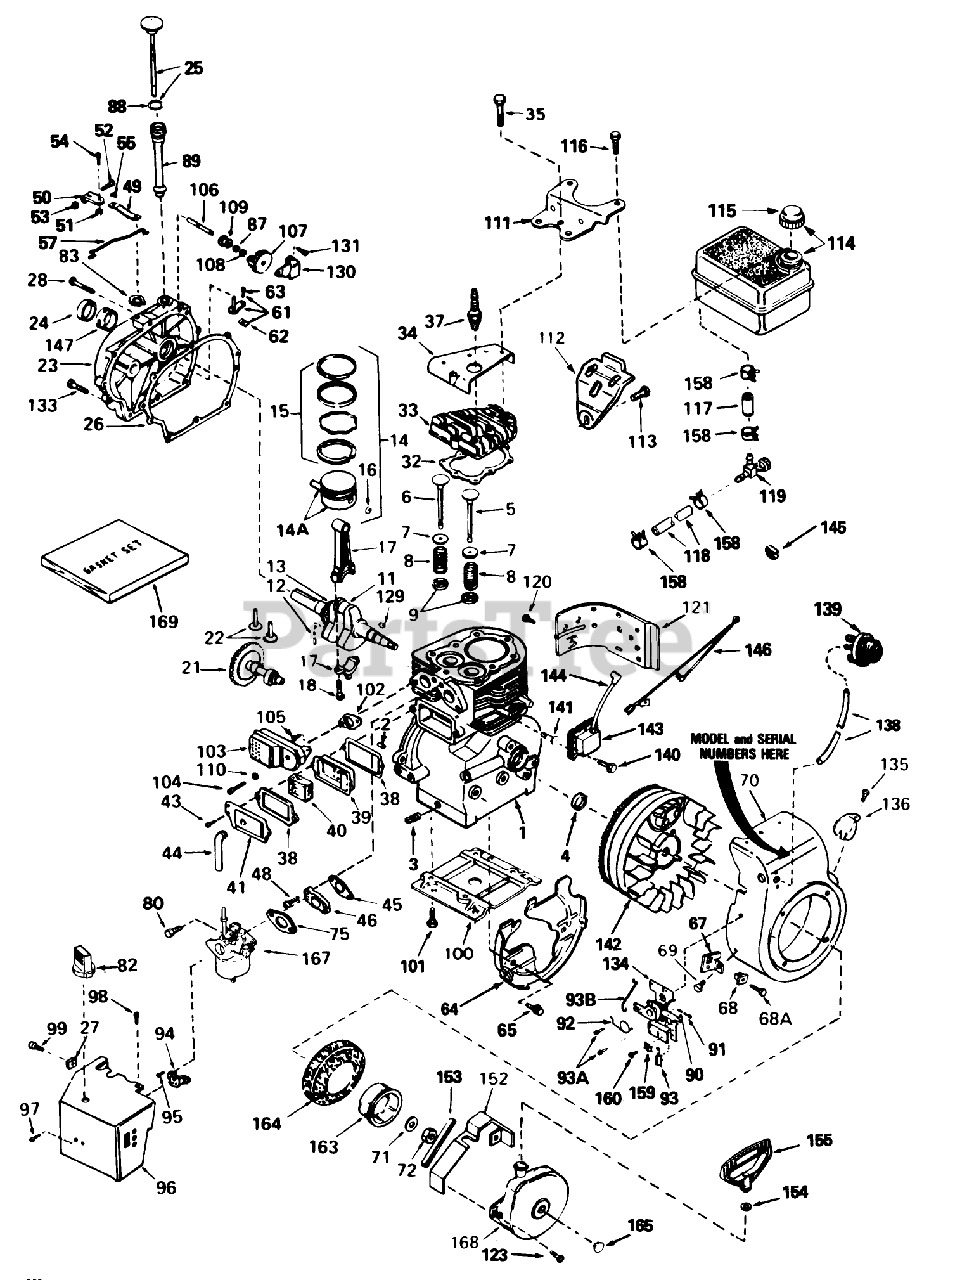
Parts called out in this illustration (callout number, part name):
1	Cylinder Assy. (Incl. Ref. #2, 3 4)
2	Pin-Dowel
3	Plug-Drain, Oil (SQH 1/4-18)
4	Oil Seal
5	Valve, Intake (Standard)(Incl. No. 9)
5	Valve, Intake (1/32" oversize)(Incl. No. 9)
6	Valve, Exhaust (Standard)(Incl. No. 9)
6	Valve, Exhaust (1/32" oversize)(Incl. No. 9)
7	Cap-Spring, Valve
8	Spring-Valve
9	Keeper-Spring, Valve
11	Crankshaft Assy. (Incl. Ref. #12 13)
12	Pin, Groove
13	Gear-Crankshaft
14	Piston, Pin Ring Assy. (Std.)(Incl. Ref. #14A, 15 16)
14	Piston, Pin Ring Assy. (.010 Oversize)(Incl. Ref. #14A, 15 16)
14	Piston, Pin Ring Assy. (.020 Oversize)(Incl. Ref. #14A,15 16)
14A	Piston Pin Assy. (Std.)(Incl. Ref. #16)
14A	Piston Pin Assy. (.010 Oversize)(Incl. Ref. #16)
14A	Piston Pin Assy. (.020 Oversize)(Incl. Ref. #16)
15	Ring Set (Std.)
15	Ring Set (.020" OS)
15	Ring Set (.010" OS)
17	Rod Assy., Connecting (Incl. Ref. #18)
18	Bolt-Connecting Rod
21	Camshaft, BCR
22	Lifter-Valve
23	Cover, Cylinder (Incl. Nos. 24 106)
24	Oil Seal
25	Dipstick, Oil (Incl. Ref. #88)
26	Gasket-Cover, Cylinder
27	Nut-U Type
28	Screw (1/4-20 x 1-1/4)
32	Gasket-Head, Cylinder
33	CYLINDER HEAD
34	Cover-Head, Cylinder
35	Screw (5/16-18 X 2-1/2)
37	Spark Plug-Resistor (R J19 L M)
38	Gasket-Breather
39	Body-Breather
40	Element-Breather
41	Cover-Valve
43	Screw
44	Tube-Breather
45	Gasket-Intake
46	481-1279 SENATOR RO
48	Screw
49	Lever-Governor
50	Clamp-Lever, Governor
51	Nut-Lock
52	Screw
53	Nut-Lock
54	Screw
55	Washer-Lock
57	Governor Link
61	Rod, Governor (Incl. Nos.62 63)
62	Yoke-Governor
63	Screw (6-40x5/16)
64	Baffle-Blower Housing
65	Screw (1/4-20x19/32)
67	Bracket
68	Grommet
68A	Screw
69	Screw
70	Housing, Blower (Incl. Ref. #135 136)
71	Washer-Belleville
72	Flywheel Nut
75	Gasket-Carburetor
80	Screw-Hex Hd.
82	Knob-Choke
83	Ring-Retaining
87	Washer-Flat
88	O-Ring
89	Tube Fill
90	Spring-Compression
91	Screw
92	Spring-Throttle
93	Terminal
93A	Screw (10-32 x 1/2)
93B	Link-Throttle
94	Bracket-Choke
95	Screw (10-32 x 1/2)
96	Carburetor Cover
97	Screw (8-32 X 5/16)
98	Screw (10-32x1/2)
99	Screw (8-32 x 3/8)
100	Base Engine
101	Screw
102	Gasket Exhaust
103	Muffler
104	Screw (5/16-18 X 2)
105	Screw
106	Shaft-Governor
107	Governor Gear ASM
108	Ring-Retaining
109	Spool-Governor
110	Washer
111	Plate, Fuel Tank Mounting
112	Bracket, Fuel Tank Mounting
113	Screw (1/4-20x19/32)
115	Cap, Fuel Tank
116	Screw (1/4-15x7/8)
117	Line-Fuel
118	Line-Fuel (8.62)
119	Valve-Shut Off
120	Screw
121	Extension-Blower Hsng.
123	Screw
129	Key-Flywheel
130	Bracket, Governor
131	Screw (10-24x1/2)
133	Screw
134	Control Assy., Remote Speed (Incl. Ref. #90 thru 93)
135	Screw (8-32 x 3/8)
136	Screw
138	Line-Primer
139	Primer Assy.
140	Screw
142	Flywheel
143	Solid State
144	Cover-Spark Plug
145	Clip-Wire
146	Ground Wire
147	Bushing-Crankshaft
152	Guard-Starter
153	Seal, Snowguard
154	Washer
155	Handle-Starter, Mitten Grip
158	Clamp-Line, Fuel
159	Conduit
160	Screw (10-32 x 3/8)
163	Cup-Starter
164	Screen-Starter
165	Plug-Starter
167	Carburetor (Incl. Ref. #75)
168	Starter-Rewind
169	Gasket Set (Incl. Items Marked *)
